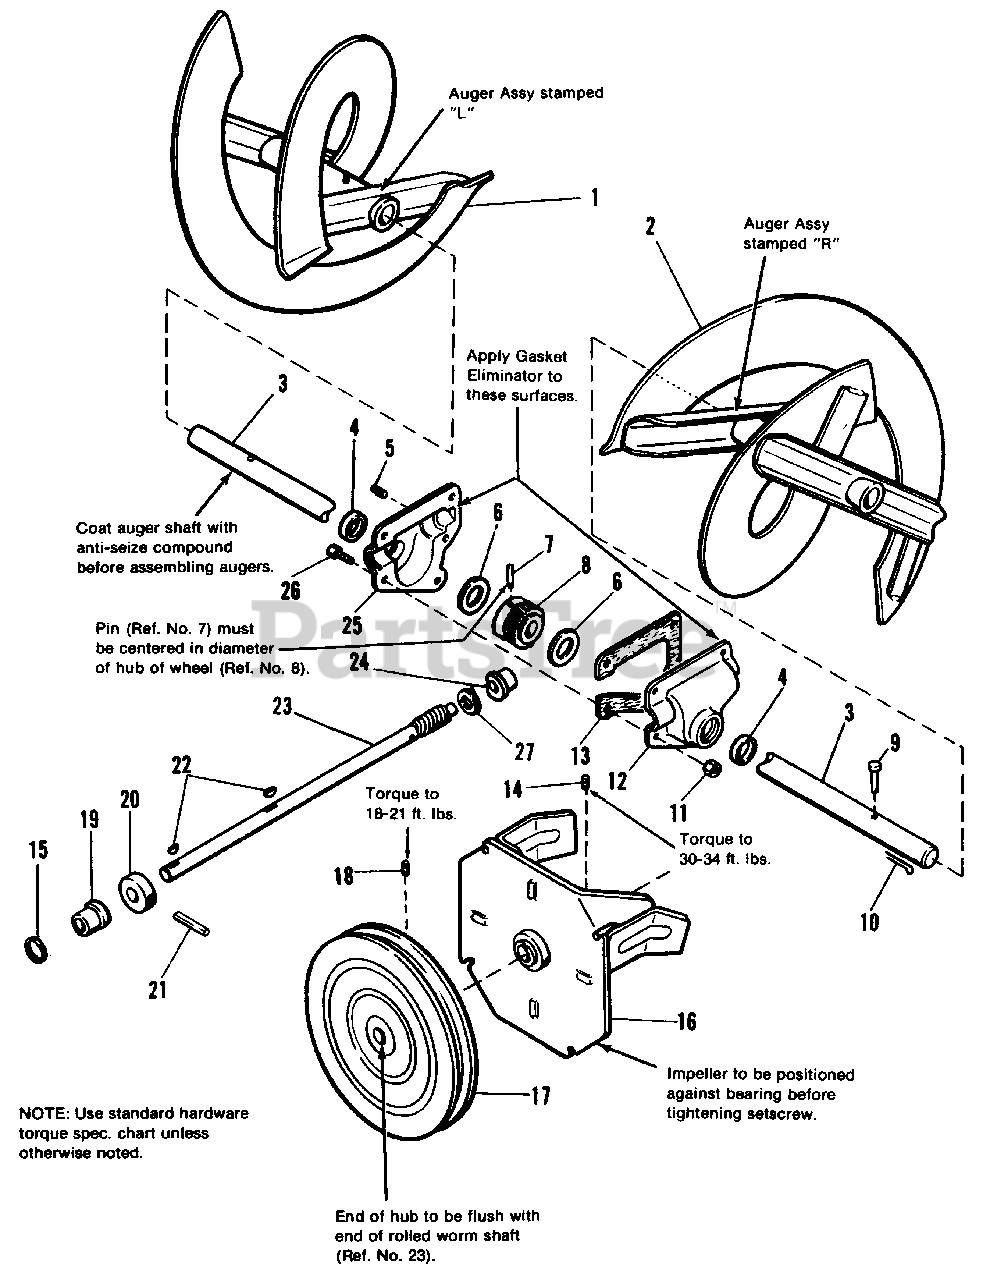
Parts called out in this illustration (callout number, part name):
1	AUGER ASSY., L.H., 60 cm (24")
1	AUGER ASSY., L.H., 70 cm (28")
1	AUGER ASSY., L.H., 80 cm (32")
2	AUGER ASSY., R.H., 60 cm (24")
2	AUGER ASSY., R.H., 70 cm (28")
2	AUGER ASSY., R.H., 70 cm (32")
3	SHAFT, Auger
5	PLUG, Pipe, 1/8
6	WASHER, Thrust
7	PIN, Drivelok, 5/16 x 1-1/2
8	WHEEL, Worm
9	PIN, Shear
10	PIN, Cotter, 3/32 x 3/4
11	LOCKNUT, Hex, 1/4-20
12	CASE, Gear, R.H.
14	SETSCREW, Sq. Hd., 3/8-16 x 1/2
16	IMPELLER ASSY.
17	PULLEY, Auger Input
18	SETSCREW, Sq. Hd., 5/16-18 x 1/2
19	BUSHING, Flange
20	COLLAR, Thrust
21	PIN, Drivlok, 3/16 x 1-1/2
22	KEY, Woodruff, 3/16 x 5/8
23	SHAFT, Roller Worm
24	BUSHING, Flange
25	CASE, Gear, L.H.
26	CAPSCREW, Hex Hd., 1/4-20 x 7/8
27	WASHER, Thrust
